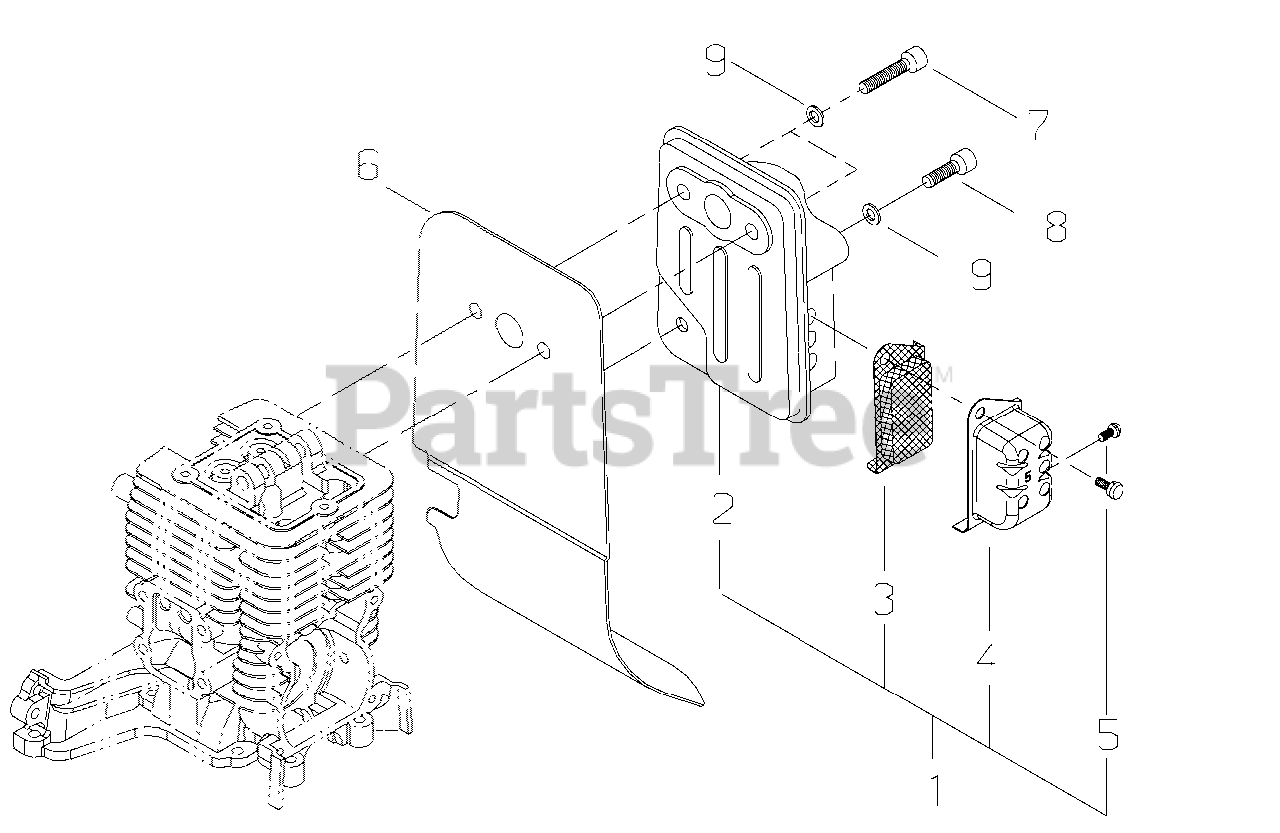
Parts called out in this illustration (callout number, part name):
1	MUFFLER ASSY
2	MUFFLER
3	SCREEN, SPARK ARRESTOR
4	GUIDE, EXHAUST
5	SCREW - 4X6
6	SHIELD, EXHAUST
7	SCREW - 5X25
8	SCREW - 5X16
9	WASHER - 5
